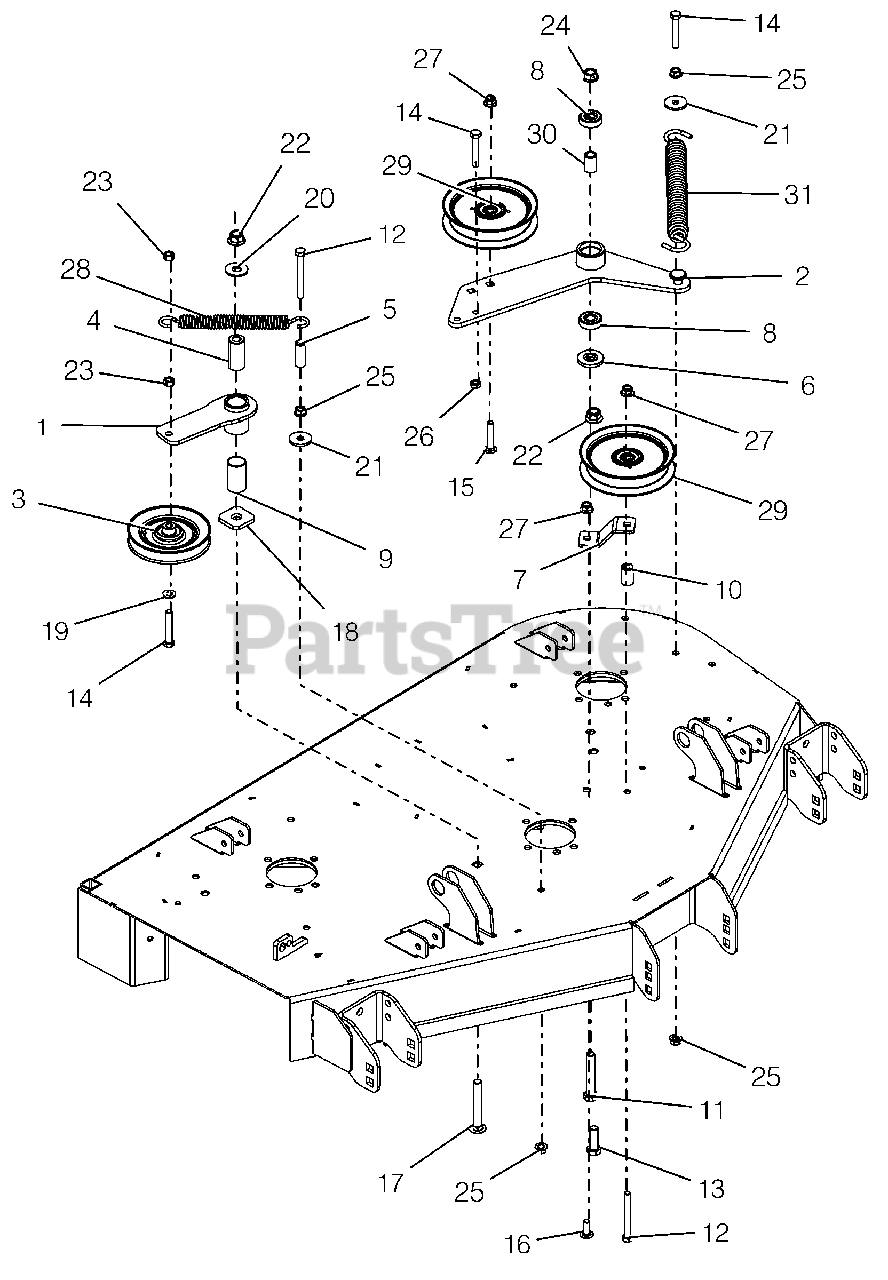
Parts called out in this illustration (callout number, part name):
1	WMT, IDLER ARM - BLACK
2	DECK PTO IDLER ARM WLDMT - BLK
3	IDLER, V-5.00"
4	BSHG, SPCR .502X.997X2.03 PM
5	SPACER, .375IDX.625ODX1.66 PM
6	SPACER, IDLER ARM
7	PTO FIXED IDLER MTG BRKT -RED
8	BRG-BALL .500X1.38X.437
9	BSHG, 1.00X1.125X1.937
10	BUSHING, SLV .380X.750X1.190
11	@BLT-HEX .50-13X3.00 GR5 YWZC
12	@BLT-HEX .38-16X3.25 GR5 YWZC
13	@BLT-HEX .50-13X1.50 GR5 YWZC
14	@BLT-HEX .38-16X2.25 GR5 YWZC
15	BLT-RDHDSQNK .38-16X2.00 SHTYW
16	@BLT-RDHDSHSQNK.38-16X1.0 G5YZ
17	@BLT-RDHDSQNK .50-13X3.50 G5YZ
18	WSHR-FLT .640X1.75X.250
19	@WSHR-FL-STL.406X.812X.065 YWZ
20	@WSHR-FL-STL.563X1.38X.109YWZC
21	WSHR-FL-STL .406X1.375X.135 YZ
22	@NUT-LK-NYL-FLG .50-13 YWZC
23	@NUT-LK-CTR .38-16 YWZC
24	NUT-LK-CTR-FLG .50-13 YWZC
25	@NUT-SPNLK-FLG .375-16 YWZC
26	NUT-HEX-JAM .375-16 YWZC
27	@NUT-LK-NYL-FLG .38-16 YWZC
28	SPRING, EXTENSION
29	IDLER, FLAT 5.00"
30	SPACER .510 X .75 X 1.1485
31	SPRING, EXTENSION
